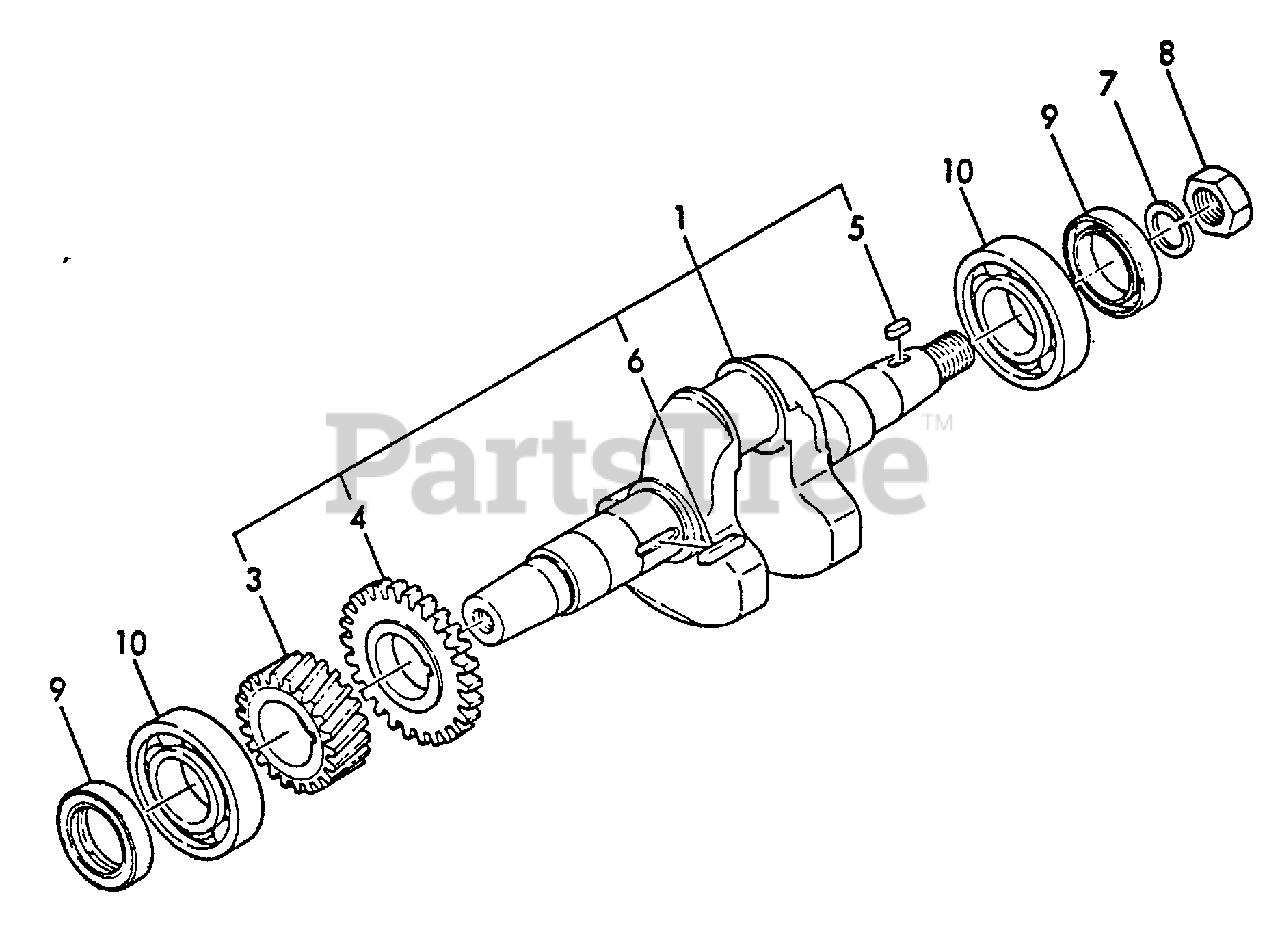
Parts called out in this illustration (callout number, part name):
1	CRANKSHAFT ASSY
3	GEAR, CRANKSHAFT
4	GEAR, BALANCER
5	KEY - 4X10
6	KEY - 4X24
7	LOCKWASHER - 10
8	NUT - 16
9	SEAL, OIL
10	BEARING, BALL - 6206C4
